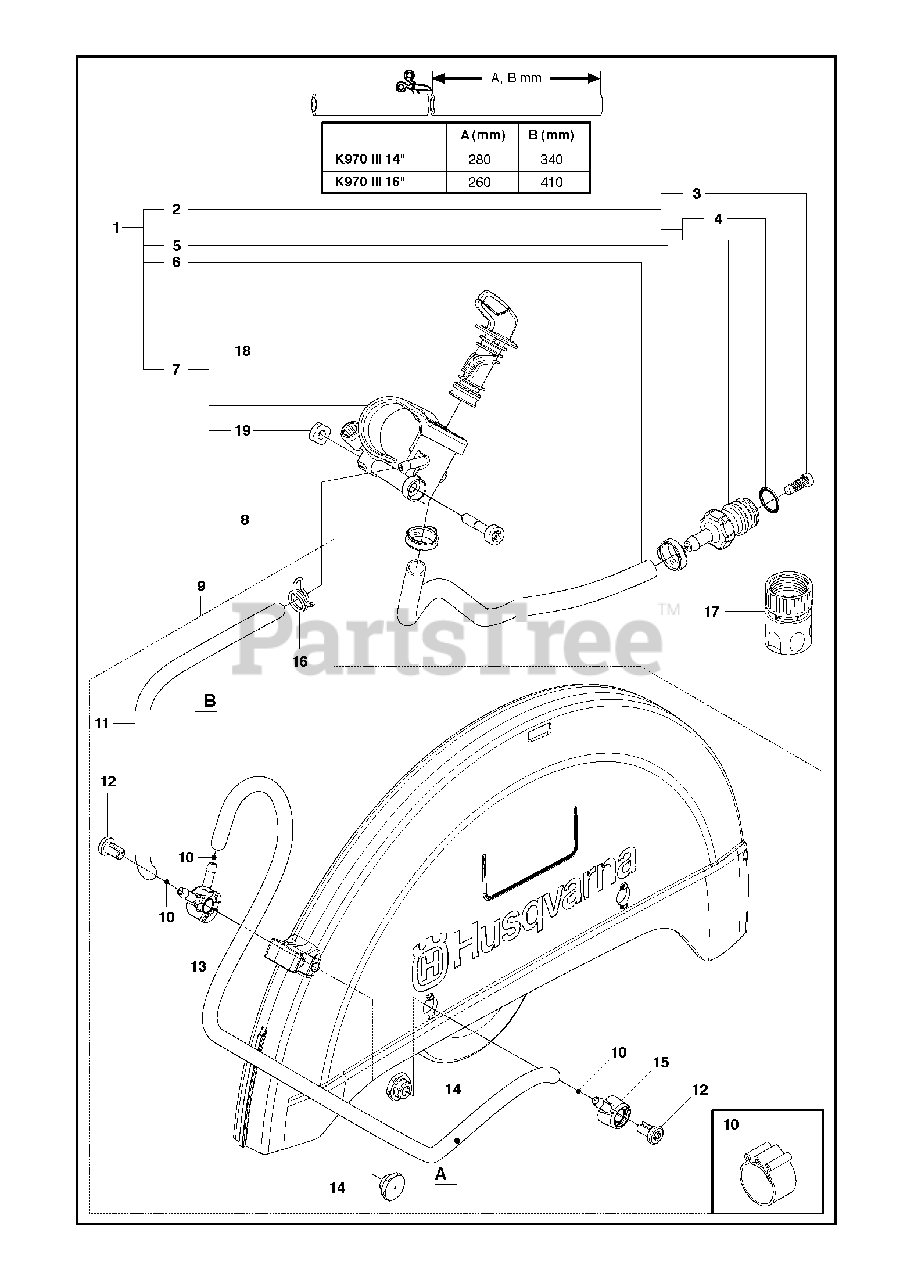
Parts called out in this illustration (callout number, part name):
8	SCREW ITXSCM
10	HOSE CLAMP
12	SCREW ITXSCM
17	COUPLER"1/2"""
17	COUPLER"GHT 3/4"""
18	LEVER ASSY
